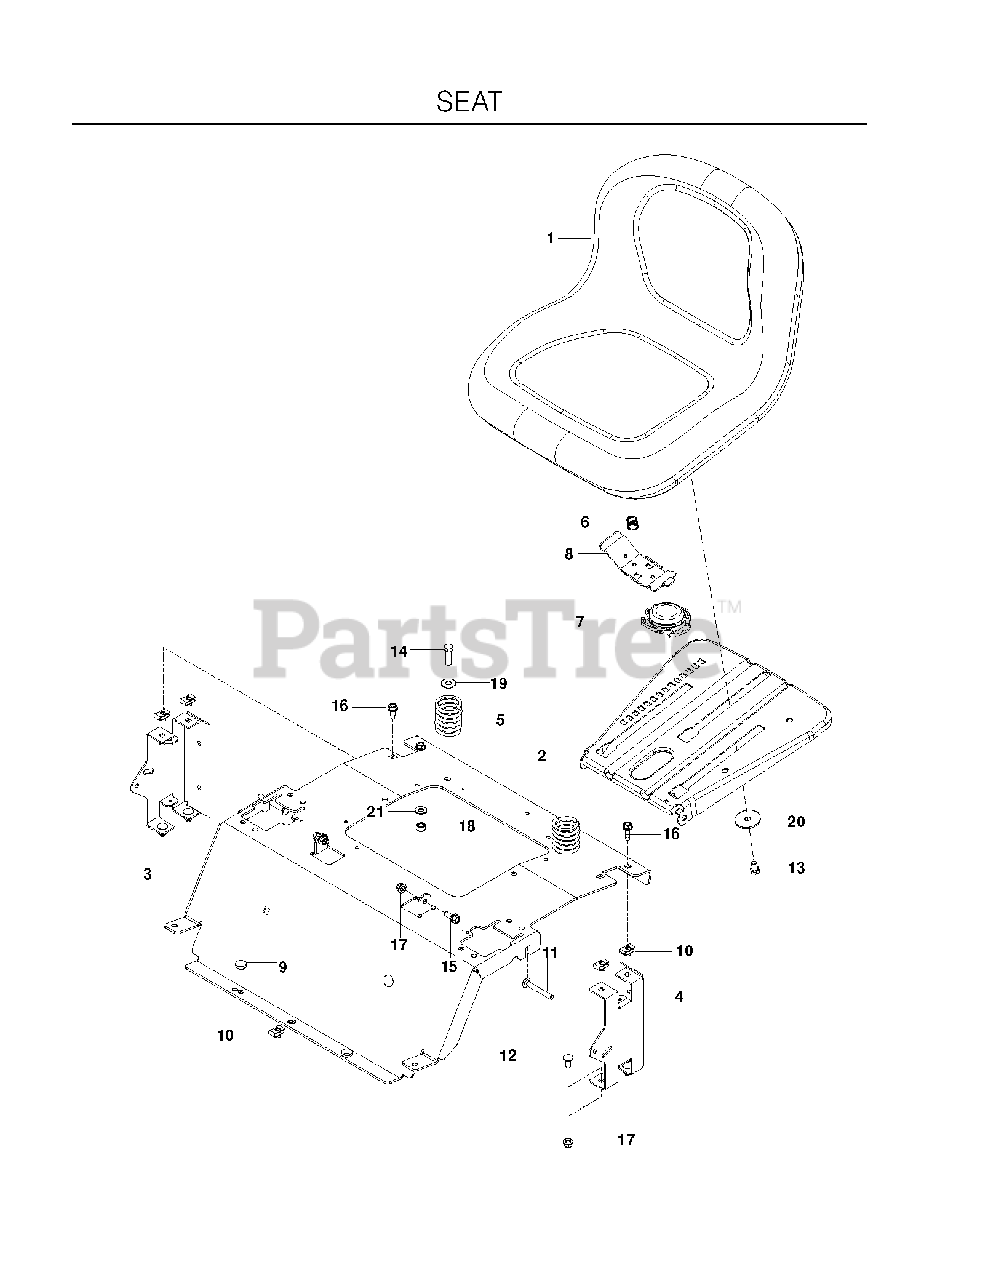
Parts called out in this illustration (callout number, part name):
1	RP SEAT, TH150, GREY, MILSCO
2	PAN.ASM.SEAT.3PT
3	SUPPORT SEAT ORANGE
4	SUPPORT, REAR SEAT, BLACK
5	SPRING, SEAT
6	SPRING.LATCH.SEAT.TEX
7	SWITCH, SEAT N/C
8	HANDLE.SLIDE.SEAT.TEX.BLACK
9	GROMMET, BUMPER
10	U-CLIP 5/16-18 NUT RETAINER
11	RHSNB 5/16-18 X 2-1/2 GR5 ZD
12	BOLT 5/16C X 3/4" CARRIAGE
13	HCS 3/8-16 X 5/8 GR 5 ZD
14	HCS 3/8C X 1 1/4 GR5
15	BOLT, SHOULDER
16	BOLT 5/16-18 X 3/4
17	5/16-18 NYLOC FLANGE NUT
18	NUT 3/8-16 NYLOC
19	RP WASHER 3/8 FLAT
20	WASHER, 3/8 SPEC
21	WASHER 3/8 SAE FLAT
